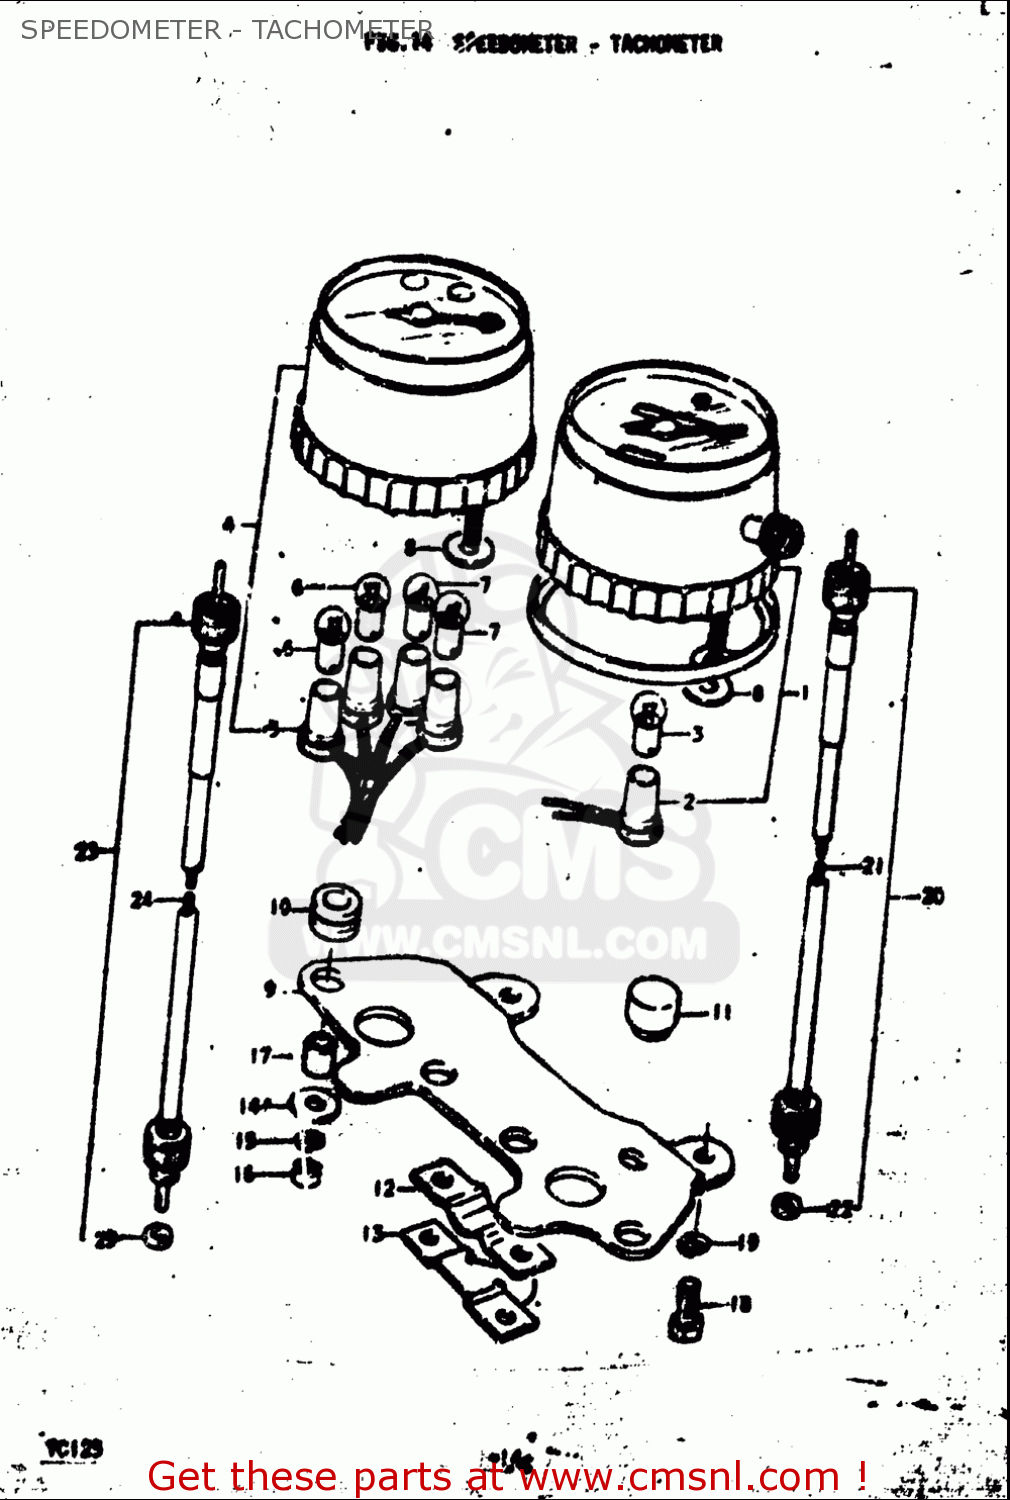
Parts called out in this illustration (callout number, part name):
3	BULB(6V/3W)
5	SOCKET,TACHOMETER
6	BULB(6V/3W)
7	BULB(6V1.7W,STANLEY,A61A)
8	WASHER(5.5X16X1.2)
10	CUSHION
14	WASHER(5.5X16X1.2)
15	WASHER,LOCK
16	NUT
17	SPACER,METER NO.2
18	BOLT
19	WASHER,LOCK
20	CABLE ASSY,SPEEDOMETER
21	CABLE ASSY,SPEEDOMETER
22	SEAL,OIL METER CABLE
23	CABLE ASSY,TACHOMETER
24	CABLE ASSY,TACHOMETER
25	SEAL,OIL SPEEDOMETER CABLE
